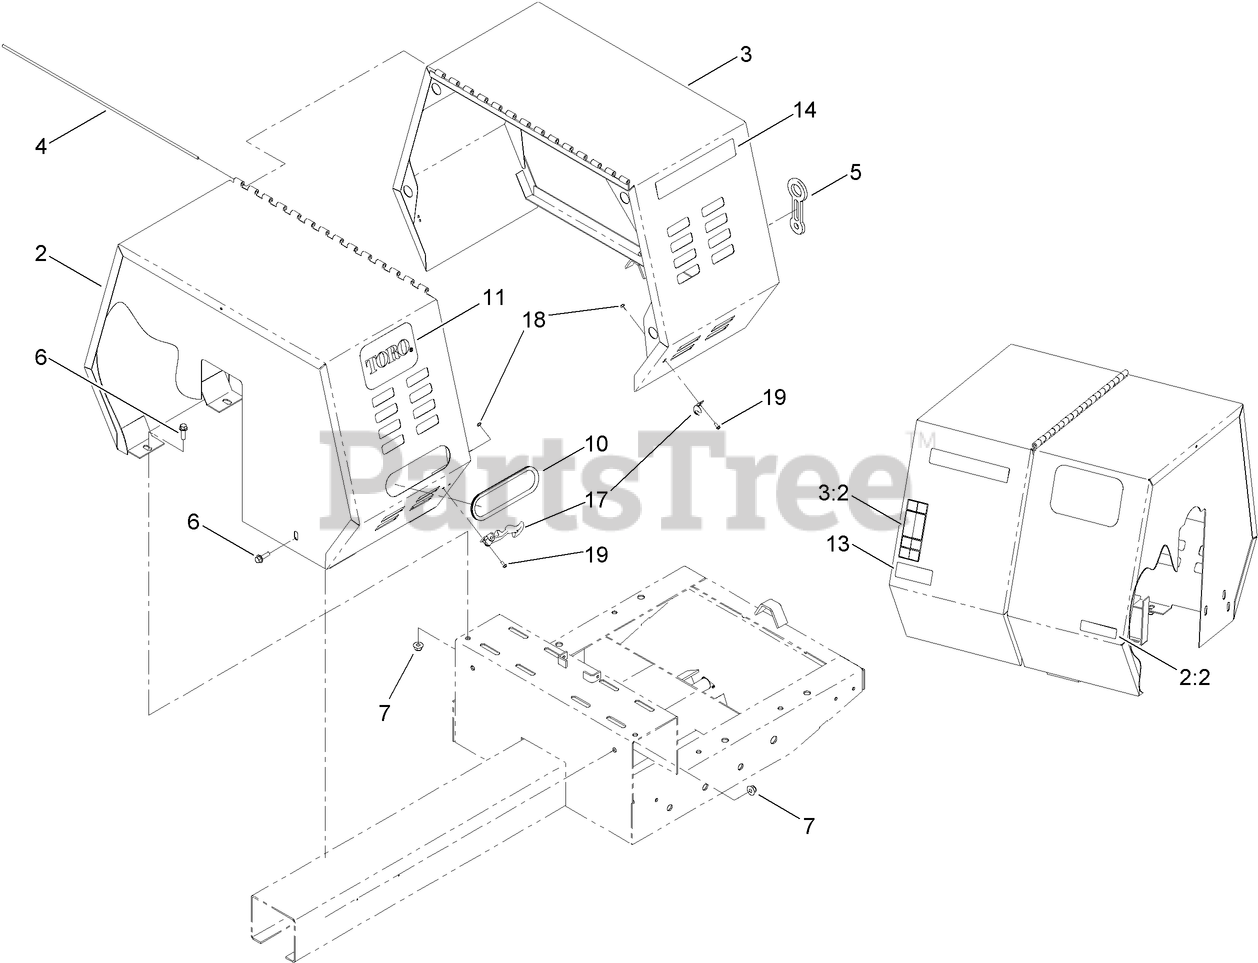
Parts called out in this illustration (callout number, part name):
2	STATIONARY COWL ASM
2:2	DECAL-ARRESTER, SPARK
3	MOVABLE COWL ASM
3:2	DECAL-WARNING
5	LATCH-RUBBER
6	SCREW-HHF
7	NUT-HF, NI
10	TRIM-LID
11	DECAL
14	DECAL-MM-12511H
17	LATCH-FLEX, DRAW
18	NUT-LOCK, NI
19	SCREW-HWH
